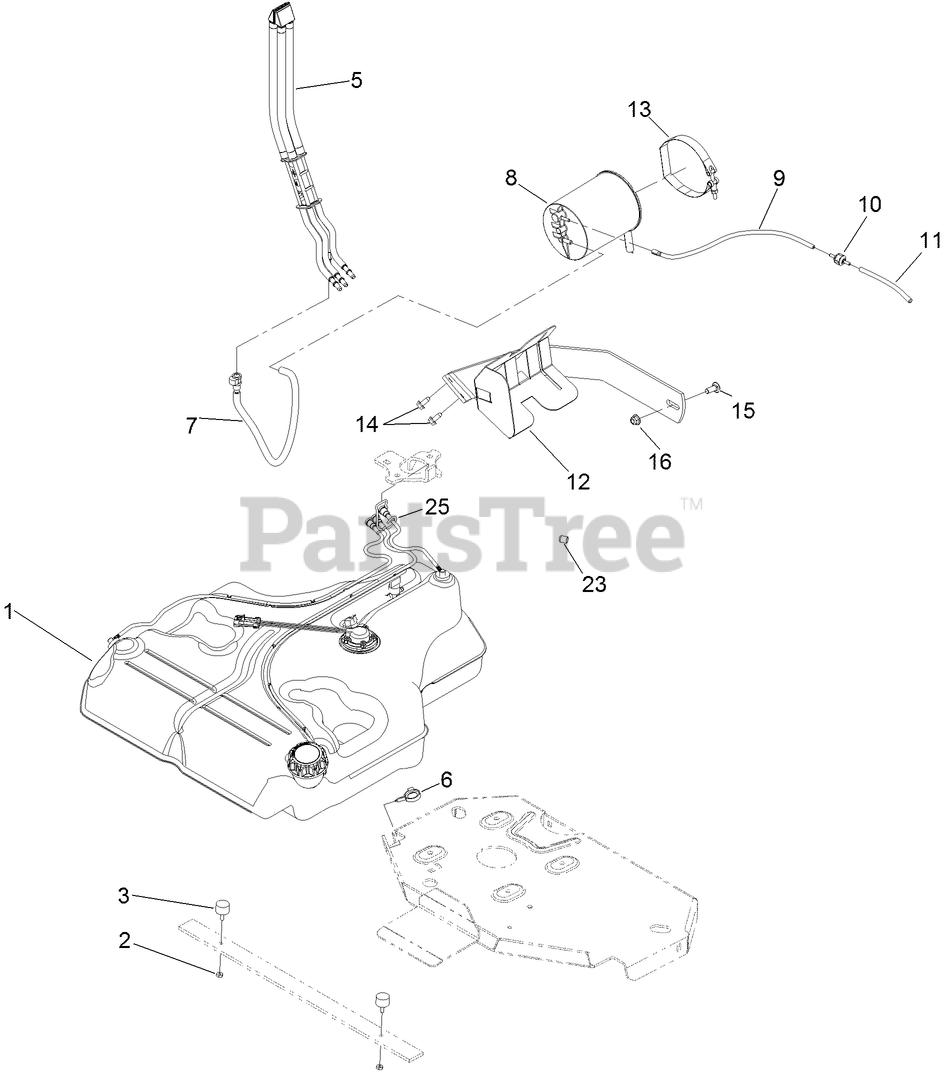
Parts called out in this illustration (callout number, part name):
1	FUEL TANK ASM
2	NUT-JAM
3	BUMPER-RUBBER (W/ STUD)
5	FUEL MANIFOLD VENT ASM
6	CLAMP-HOSE
7	VENT HOSE ASM
8	CANISTER-CARBON, 1200CC
9	HOSE-VENT, FORMED
10	VALVE-CHECK, VACUUM
11	HOSE-VENT, FORMED
12	MOUNT-CANISTER
13	CLAMP-T-BOLT
14	SCREW-HWHTF
15	SCREW-CARR
16	NUT-HF, NI
23	PLUG-PORT
25	RETAINER-LINE, VAPOR
